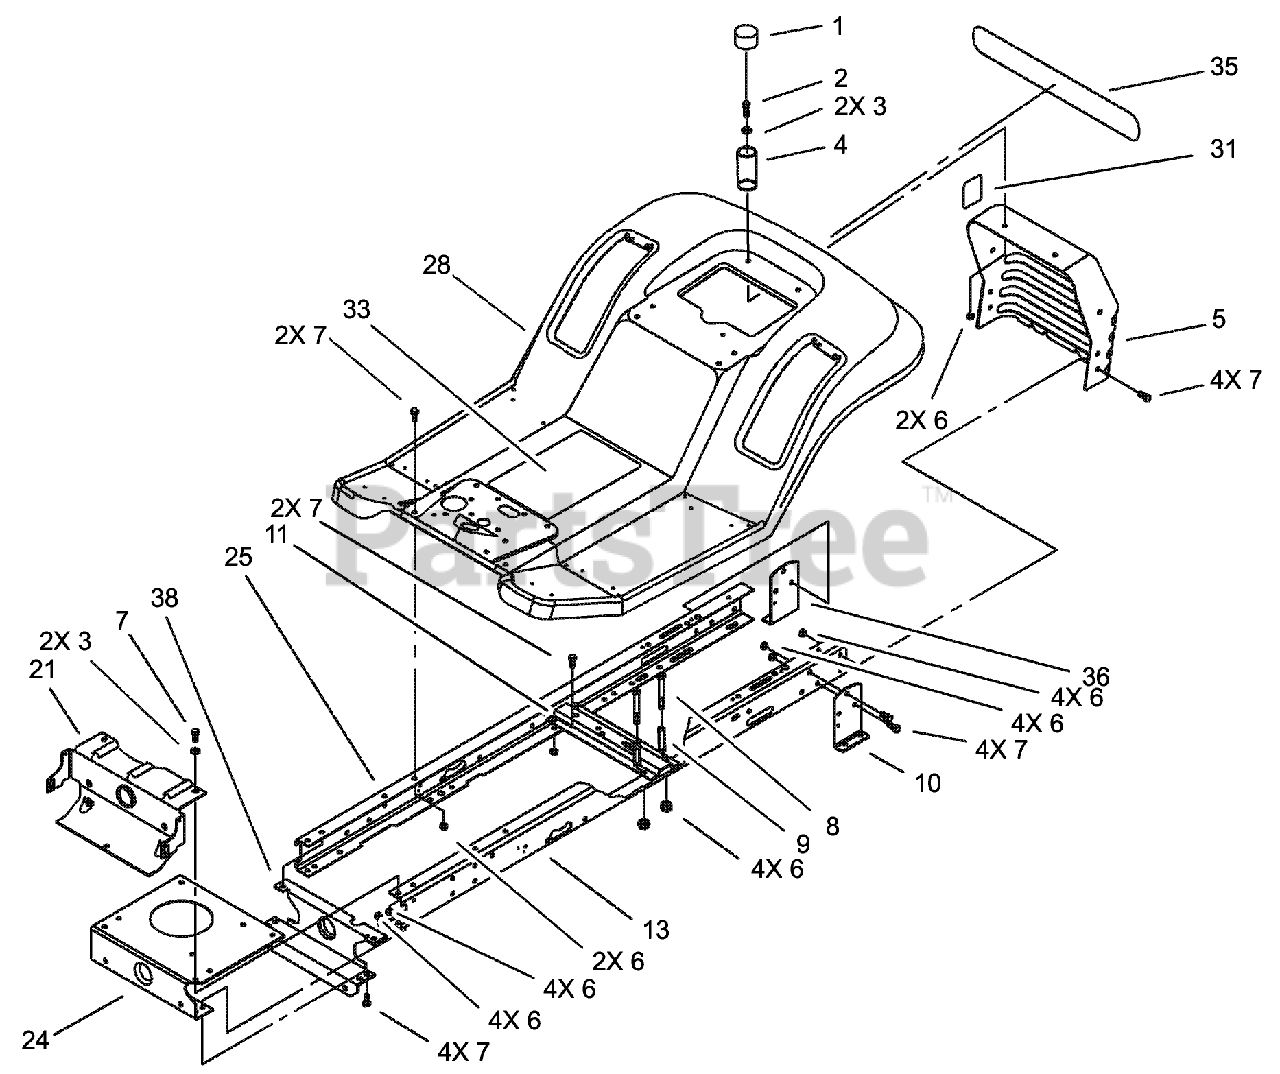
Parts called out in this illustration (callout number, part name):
1	CAP-PROTECTOR
2	SCREW-HH
3	WASHER-PLAIN
4	SPRING-COMPRESSION
5	SUPPORT-SEAT/REAR HITCH
6	NUT-LOCK, NI
7	SCREW-HH
8	SCREW-HH
9	SPACER
10	BRACKET-MOUNTING, LH TRANSAXLE
11	BRACKET-IDLER PIVOT
13	RAIL-FRAME, LH
21	SUPPORT-AXLE, FRONT
24	PLATE-MOUNTING, ENGINE
25	RAIL-FRAME, RH
28	REAR BODY ASM
31	DECAL-VALVE, DUMP
33	DECAL-INSTRUCTION
35	DECAL-REAR, BODY
36	BRACKET-MOUNTING, RH TRANSAXLE
38	SUPPORT-REAR
